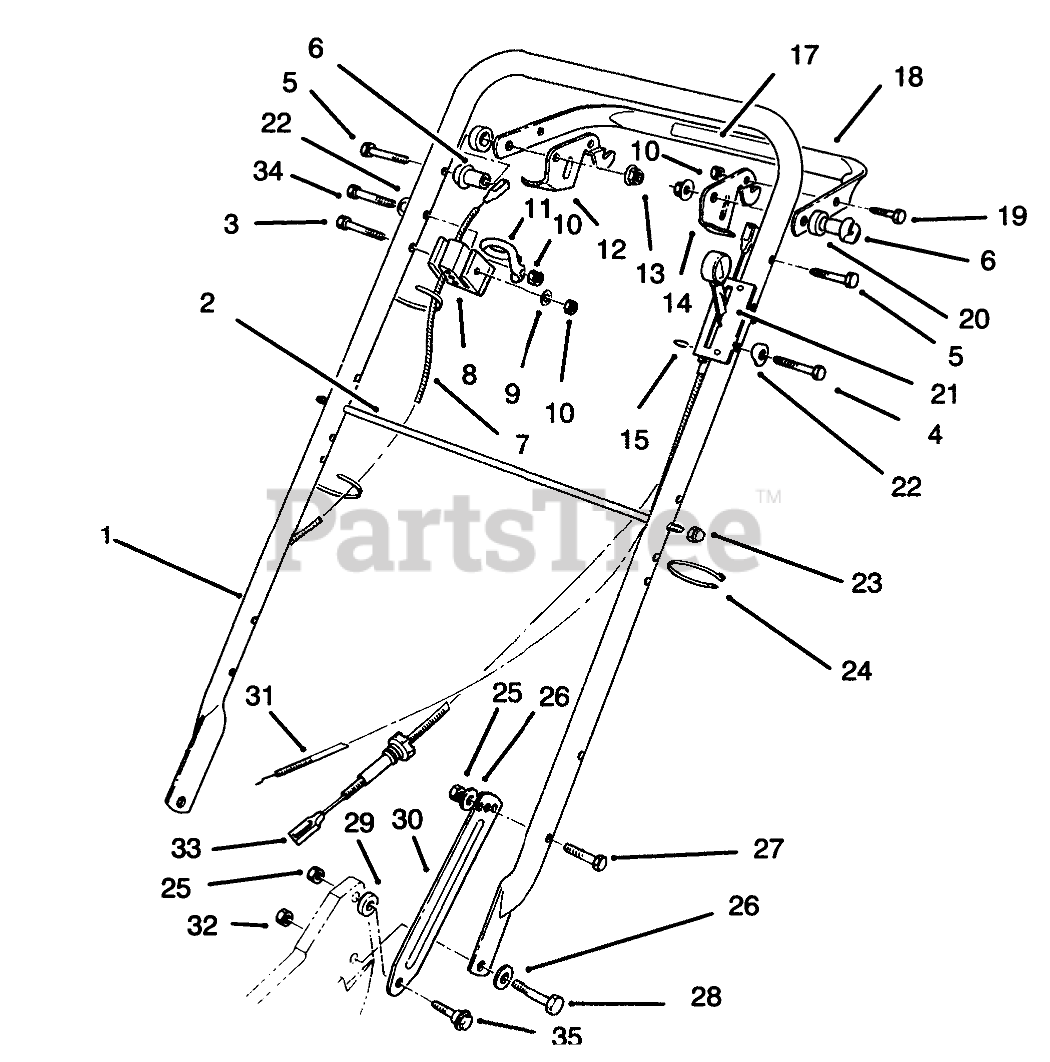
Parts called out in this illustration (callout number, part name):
1	Handle
2	ROD-SUPPORT, BAG
3	SCREW-HH
4	SCREW-HH
5	SCREW-HH
6	SPACER-SUPPORT
7	Cable-Brake
8	SUPPORT-CABLE
9	WASHER-FLAT
10	NUT-LOCK, NI
11	GUIDE-ROPE
12	LEVER-CONTROL
13	NUT-LOCK, NI
14	LEVER-CONTROL
15	E-RING
17	DECAL/TRACTION CONTROL
18	Bar-Control
19	SCREW-HH
20	SPACER-NYLON
21	CONTROL-THROTTLE
22	WASHER
23	NUT-CAP
24	TIE-CABLE
25	NUT-LOCK, NI
26	WASHER-BELLEVILLE
27	SCREW-HH
28	SCREW-HH
29	SPACER
30	Latch-Handle
31	CABLE-THROTTLE
32	NUT-LOCK, NI
33	CABLE-TRACTION
34	SCREW-HH
35	SCREW-SHOULDER
